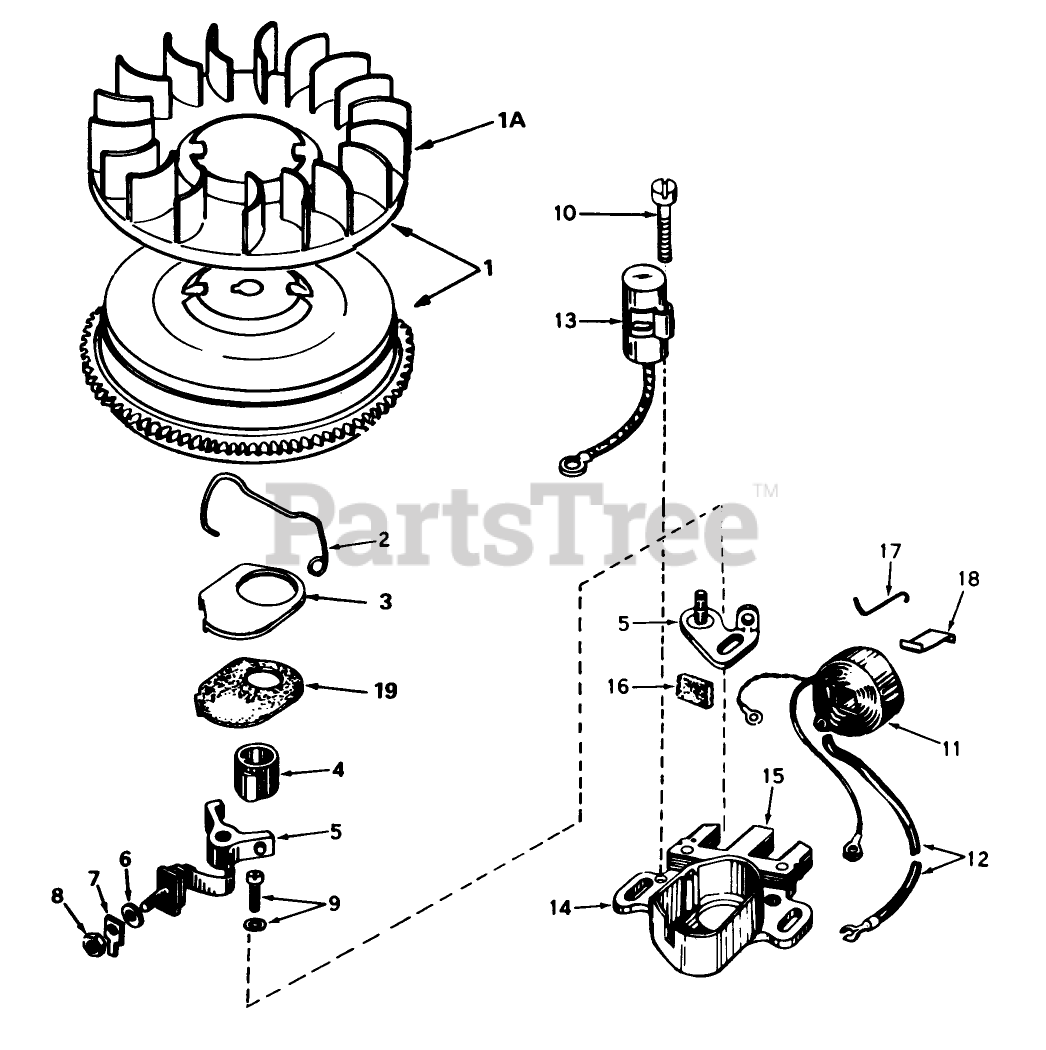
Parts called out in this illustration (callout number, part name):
1	Flywheel (Incl. No. 1A)
1A	Fan
2	Spring Breaker Box
3	Cover-Dust
4	Cam-Breaker
5	Breaker Assy.
6	Washer
7	Terminal, Ground
8	DECAL
9	Breaker Screw
10	Condenser Screw
11	Coil Assy. (Incl. No. 12)
12	Wire, Lead
13	Condenser
14	Core Plate
15	Stator Assy. (Incl. Ref. #2 thru 11, 13, 14, 16, 17 19)
16	Felt,Cam Wiper
17	Clip, Coil
18	Spring Coil Wedge
19	Gasket-Dust Cover
